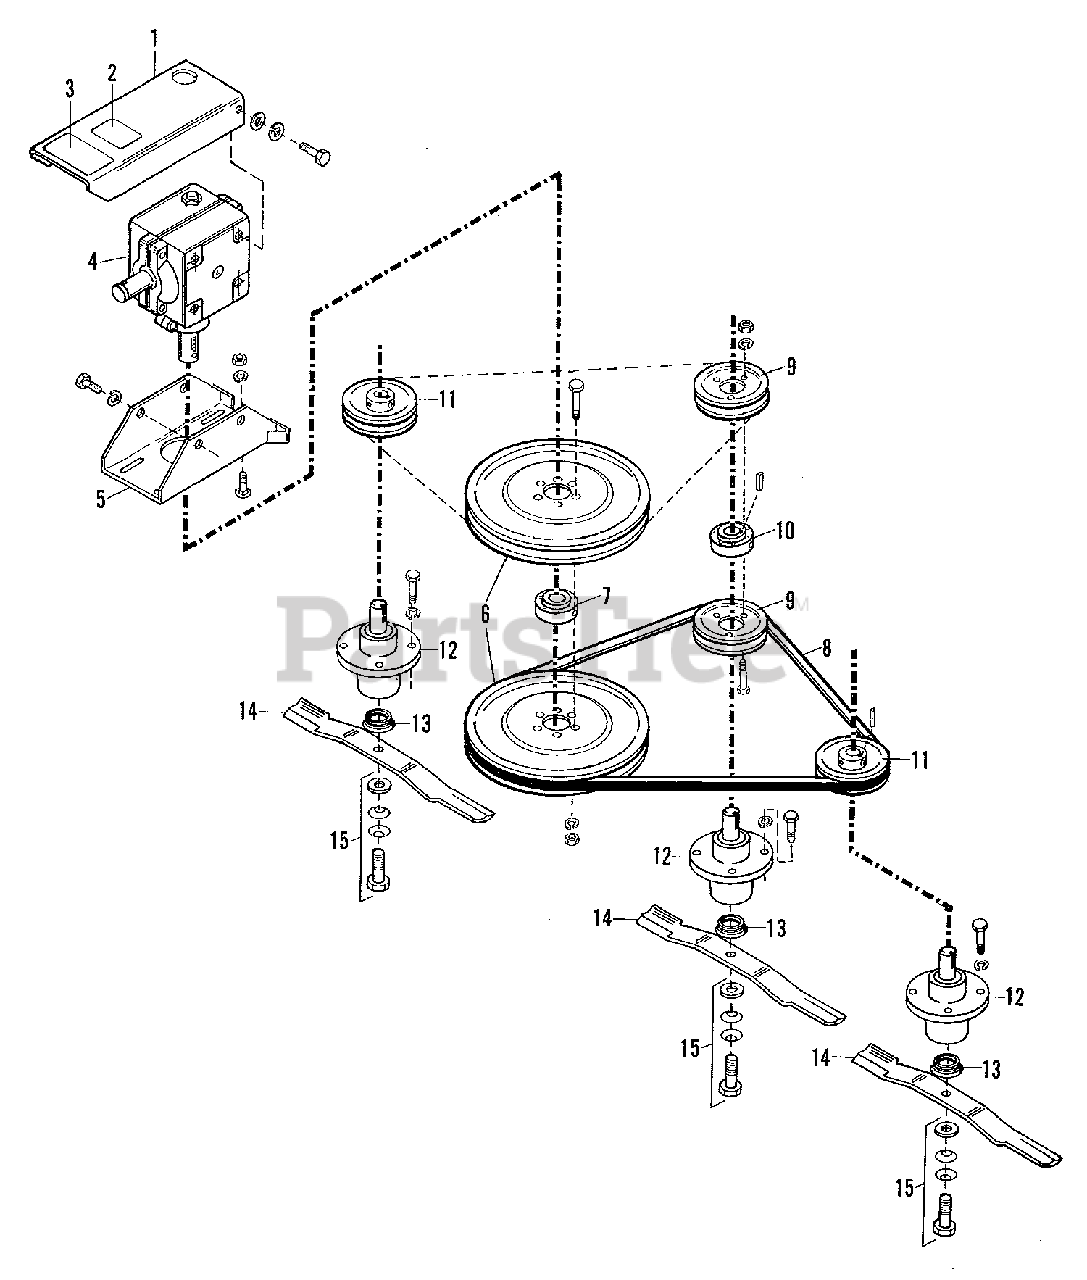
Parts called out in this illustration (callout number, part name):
1	SHIELD, Universal
1	CAPSCREW, 1/2NC x 1
1	LOCKWASHER, 1/2
1	WASHER, Plain, 13/32 x 13/16 x 1/16
2	DECAL, Warning (PTO Shield, "R.P.M")
3	DECAL, Warning ("Do Not Remove Shield)
4	GEARBOX ASSEMBLY, Complete
4	CAPSCREW, 1/2NC x 1
4	LOCKWASHER, 1/2
5	BRACKET, Gearbox
5	BOLT, Carriage, 3/8NC x 1
5	WASHER, Plain, 13/32 x 13/16 x 1/16
5	LOCKWASHER, 3/8
6	SHEAVE, 13" O.D.
6	CAPSCREW, 5/16NC x 1-3/4, Full Thread
6	LOCKWASHER, 5/16
6	NUT, 5/16NC
7	CAPSCREW, Socket Head, 3/8NC x 2-1/2, Gr. 8
7	NUT, Lock, 3/8NC
8	V-BELT (For 5-1/2" O.D. Sheave)
8	V-BELT (For 4-1/2" O.D. Sheave)
9	SHEAVE, 5-1/2" O.D.
9	SHEAVE, 4-1/2" O.D.
9	CAPSCREW, 5/16NC x 1-3/4
9	LOCKWASHER, 5/16
9	NUT, 5/16NC
10	CAPSCREW, Hex Socket, 5/16NC x 1-1/2
10	NUT, Jam, 5/16NC
10	KEY, 3/16 Square x 1-1/4
11	SHEAVE, 5-1/2" O.D.
11	SHEAVE, 4-1/2" O.D.
11	CAPSCREW, Hex Socket, 5/16NC x 1-1/4
11	NUT, Jam, 5/16NC
11	KEY, 3/16 Square x 1-1/4
12	SPINDLE ASSEMBLY
12	CAPSCREW, 1/2NF x 1
12	LOCKWASHER, 1/2
13	WASHER, Shoulder
15	CAPSCREW, 5/8NC, L.H. Thread
15	WASHER, Plain, 11/16 x 1-3/4 x 1/8
15	WASHER, Cup, 5/8
